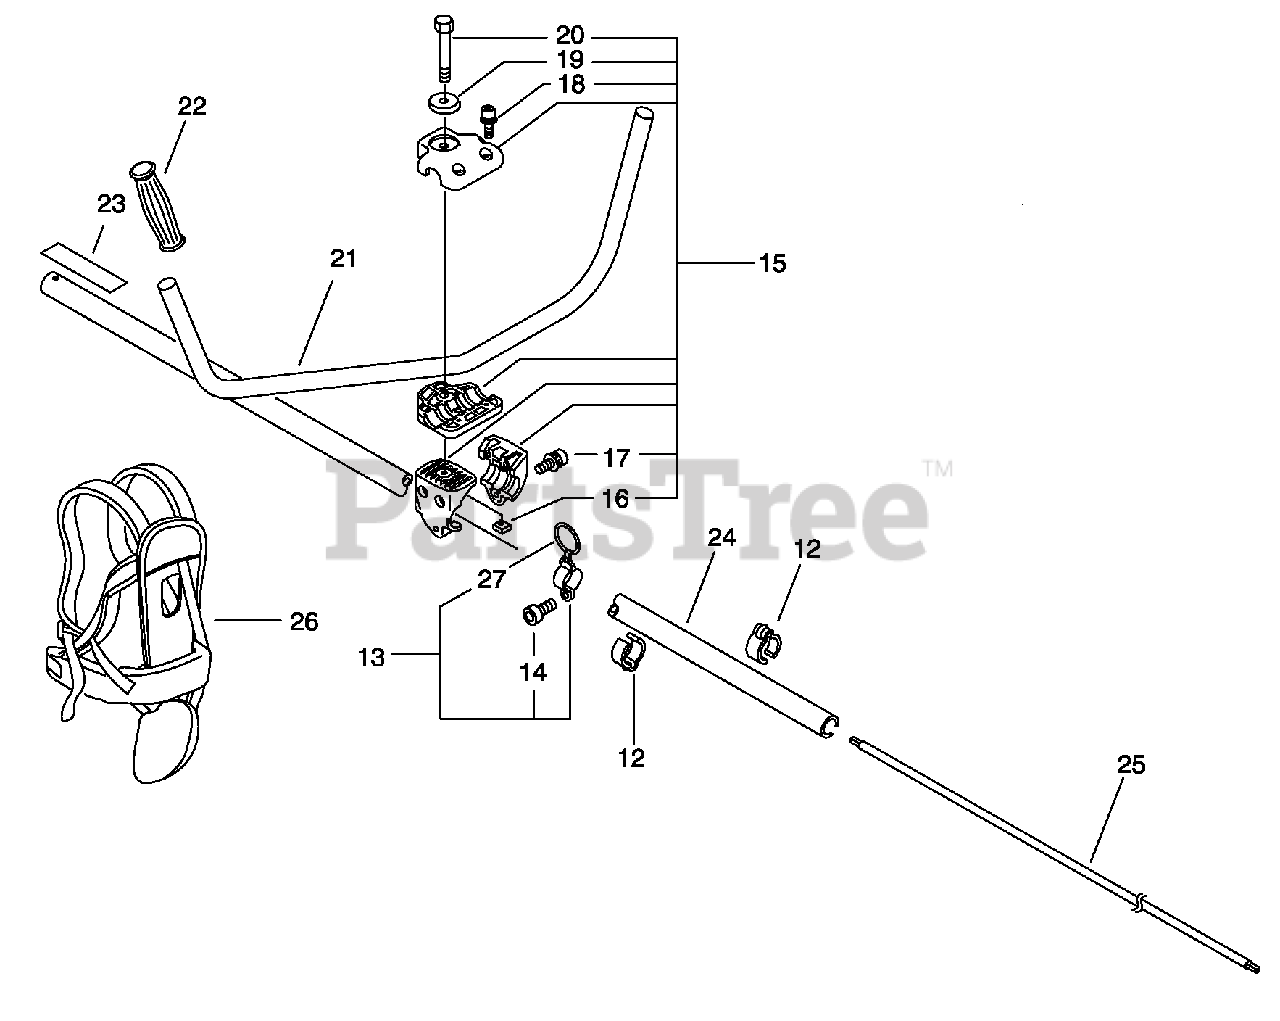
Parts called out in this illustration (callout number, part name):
13	HANGER ASSY
14	SCREW - 5X12
15	HANDLE BRACKET KIT
17	SCREW - 5X30
18	SCREW - 5X20
19	WASHER - 8
20	BOLT - 8X55
21	U-HANDLE
22	GRIP, HANDLE
23	LABEL - CAUTION
24	PIPE, MAIN
25	DRIVESHAFT
26	HARNESS ASSY
